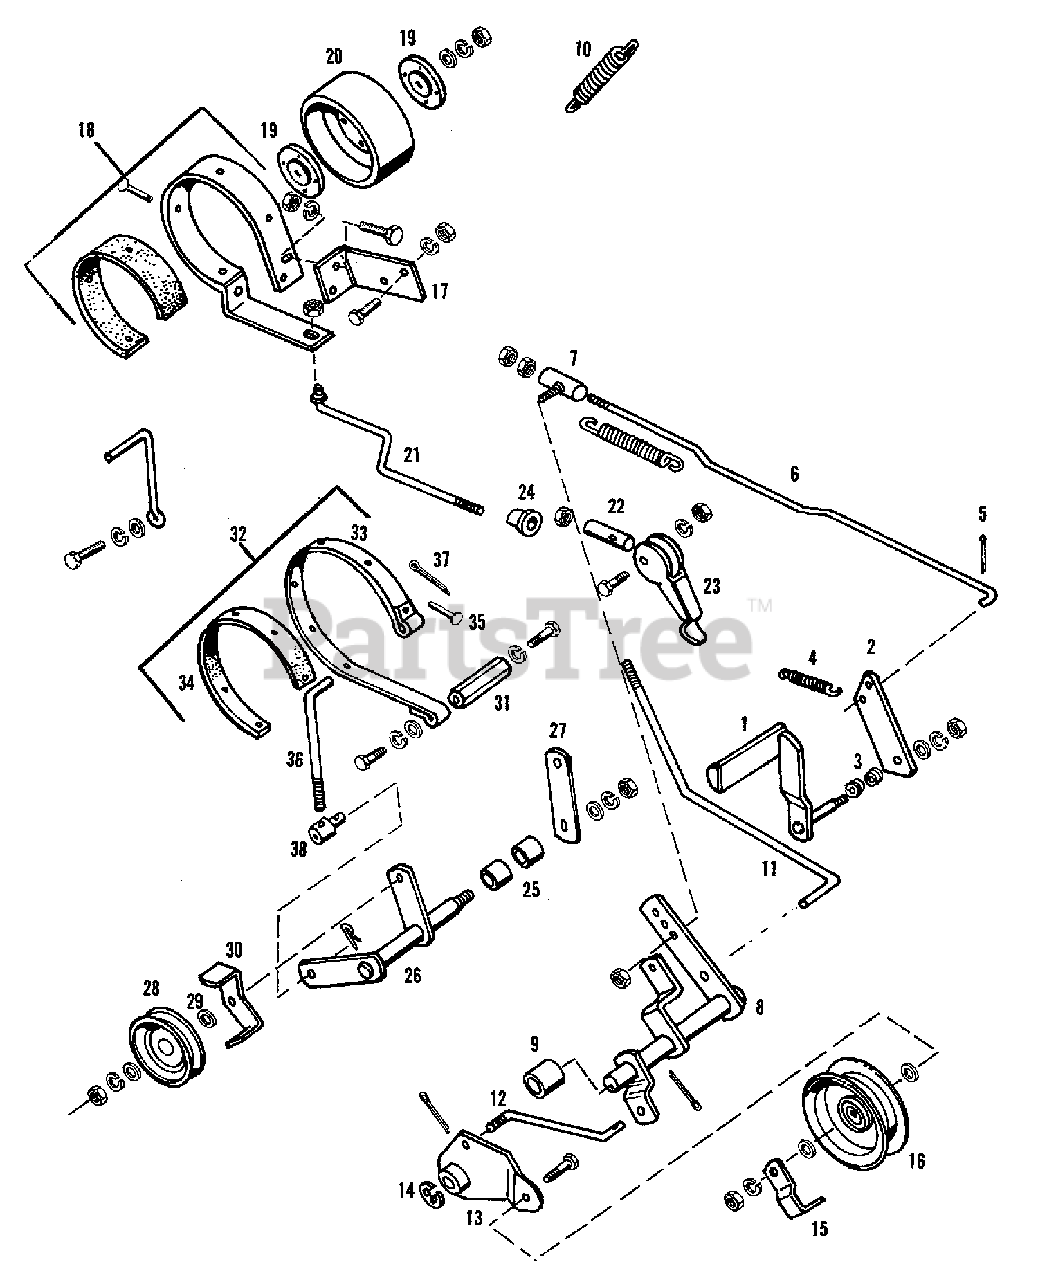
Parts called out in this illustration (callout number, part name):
1	PEDAL ASSEMBLY, Foot
2	ARM, Foot Pedal
2	WASHER, 3/8
2	LOCKWASHER, 3/8
2	NUT, 3/8NC
3	BUSHING, Flanged
5	PIN, Cotter, 3/32 x 3/4
6	ROD, Clutch & Brake
6	WASHER, 5/16
7	GUIDE ASSEMBLY, Rod
7	NUT, 5/16NC
7	NUT, 5/16NC-Lock
8	LEVER ASSEMBLY, Pivot
10	CAPSCREW, 5/16NC x 1-1/2
10	LOCKWASHER, 5/16
10	NUT, 5/16NC
11	ROD, Brake
11	PIN, Cotter 3/32 x 1
11	NUT, 3/8NC
12	LINK, Clutch
12	PIN, Cotter 3/32 x 1
13	LEVER ASSEMBLY, Idler
14	RING, External Snap (5/8" Shaft)
15	STOP, Belt Idler
16	PULLEY, Idler
16	CAPSCREW, 3/8NC x 1-1/2
16	WASHER, 3/8
16	LOCKWASHER, 3/8
16	NUT, 3/8NC
17	BRACKET, Brake Band
17	CAPSCREW, 3/8NC x 1
17	LOCKWASHER, 3/8
17	NUT, 3/8NC
18	BAND ASSEMBLY, Brake (Includes LINING)
18	LINING, Brake
18	CAPSCREW, 1/4NC x 3/4
18	LOCKWASHER, 1/4
18	NUT, 1/4NC
19	WASHER, Special
20	DRUM, Brake
20	NUT, 7/16NC
20	WASHER, 7/16
20	LOCKWASHER, 7/16
21	ROD, Parking Brake
21	NUT, 5/16NC-Lock
21	NUT, 5/16NC
23	LEVER, Parking Brake
23	CAPSCREW, 1/4NC x 1-1/4 Gr8
23	NUT, 1/4NC-Lock
23	WASHER, .531 x 1.25 x 16 Ga.
24	BEARING, Flanged
26	LEVER ASSEMBLY
27	WASHER, Plain, 3/8
27	LOCKWASHER, 3/8
27	NUT, 3/8-16
28	PULLEY, Idler
28	CAPSCREW, 3/8NC x 1-1/2
28	WASHER, Plain, 5/16
30	GUIDE, Belt
30	LOCKWASHER, 3/8
30	NUT, 3/8NC
31	ANCHOR, Brake
31	CAPSCREW, 3/8NC x 1
31	LOCKWASHER, 3/8
32	BAND ASSEMBLY, Brake
32	CAPSCREW, 3/8NC x 1-1/2
32	WASHER, Plain, 5/16
32	LOCKWASHER, 3/8
33	BAND, Brake (Not Serviced)
34	LINING, Brake (Not Serviced)
35	RIVET, #7 x 1/2 (Not Serviced)
37	PIN, Cotter, 3/32 x 3/4
